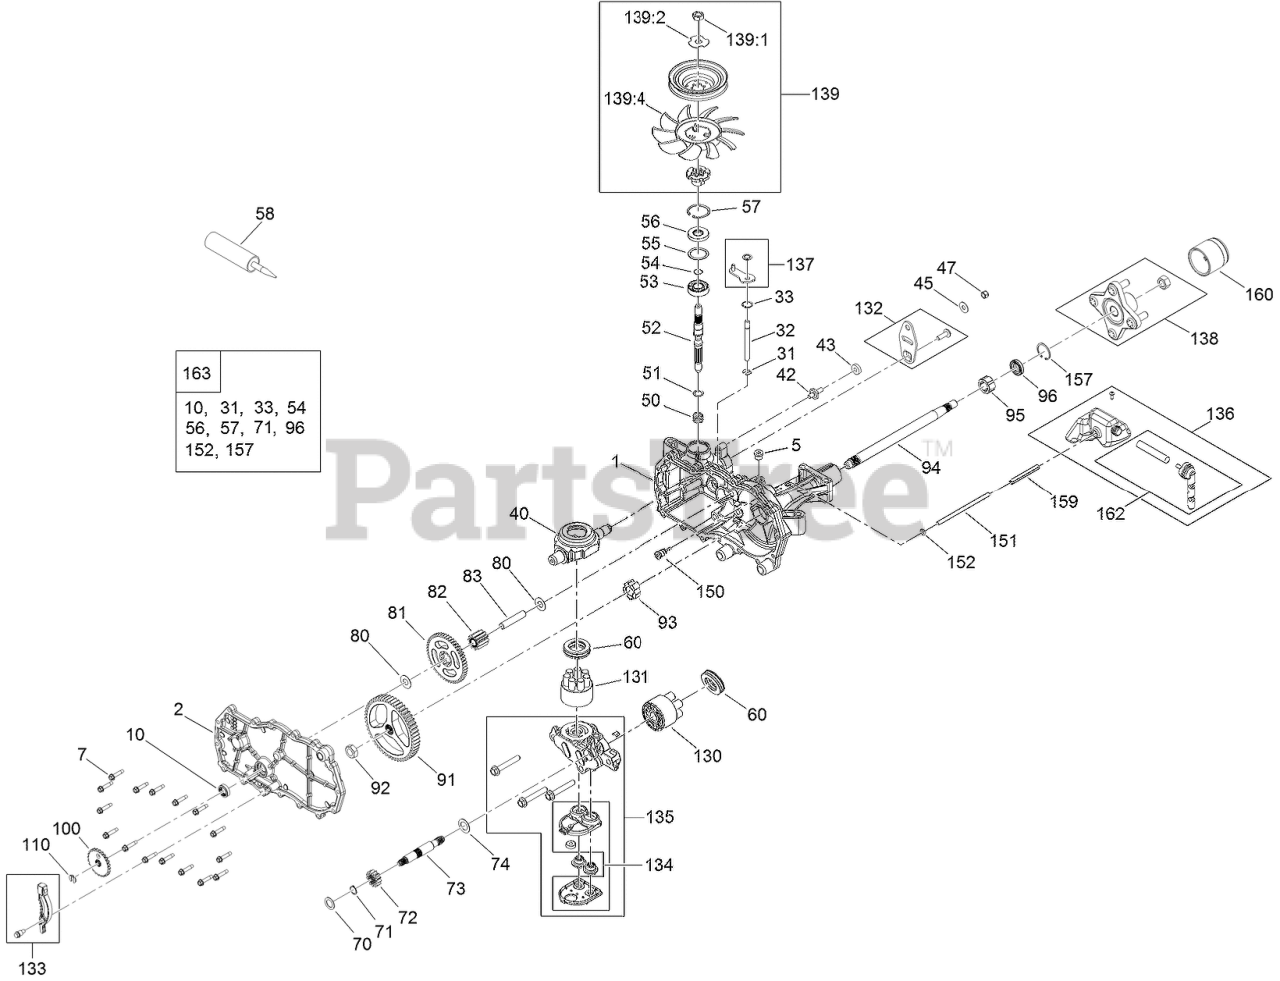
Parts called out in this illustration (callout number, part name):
1	MAIN HOUSING ASM
2	HOUSING SIDE KIT
5	PLUG-THREAD, STRAIGHT
7	SCREW-HHF
10	Seal-Lip
31	RING-RETAINING, EXTERNAL
32	ROD-BYPASS
33	RING-RETAINING, INTERNAL
40	SWASHPLATE-TRUNNION
43	PUCK-FRICTION
45	WASHER
50	SPRING-BLOCK
51	WASHER
52	SHAFT-INPUT
53	BEARING-BALL
54	RING-RETAINING
55	SPACER
56	SEAL-LIP
57	RING-RETAINING
58	SEALANT
60	BEARING-THRUST
70	WASHER-FLAT
71	RING-RETAINING
72	GEAR-PINNION, 13T
73	SHAFT-MOTOR
74	WASHER
80	WASHER
81	GEAR-10T/48T
82	GEAR-JACKSHAFT, 10T
83	PIN-JACKSHAFT
91	GEAR-BULL
92	NUT-HJ
93	BUSHING-INBOARD
94	SHAFT-AXLE
95	BEARING-SLEEVE
100	DISC-BRAKE, COG
110	RING-RETAINING, EXTERNAL
130	CYLINDER BLOCK KIT
131	PUMP BLOCK ASM
132	CONTROL ARM KIT
133	BRAKE ARM KIT
134	CENTER SECTION FILTER KIT
135	FILTER KIT
136	RH EXPANSION TANK KIT
137	BYPASS KIT
138	HUB KIT
139	FAN AND PULLEY KIT
139:1	NUT-HJ
139:2	WASHER-SLOTTED
139:4	FAN 7.0 X 10 BLADE
150	FITTING-SAE
152	O-RING
159	CASE-TUBE
160	CAP-AXLE
162	BREATHER ASM KIT
163	SEAL AND RING KIT
